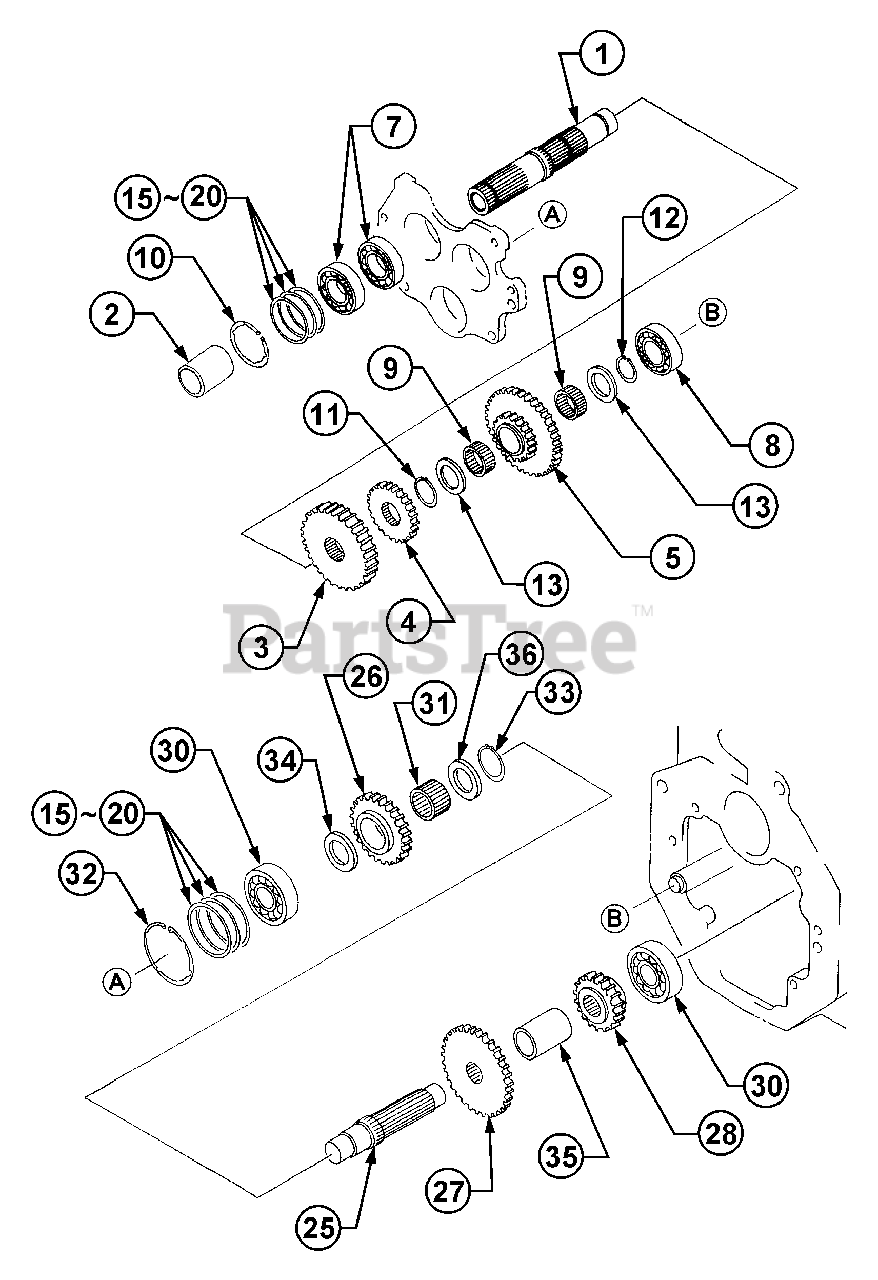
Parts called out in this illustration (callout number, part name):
7	Bearing, Ball
8	Bearing, Ball
9	Bearing, Needle
15	Liner, t=0.15
30	Bearing, Ball
31	Bearing, Needle
